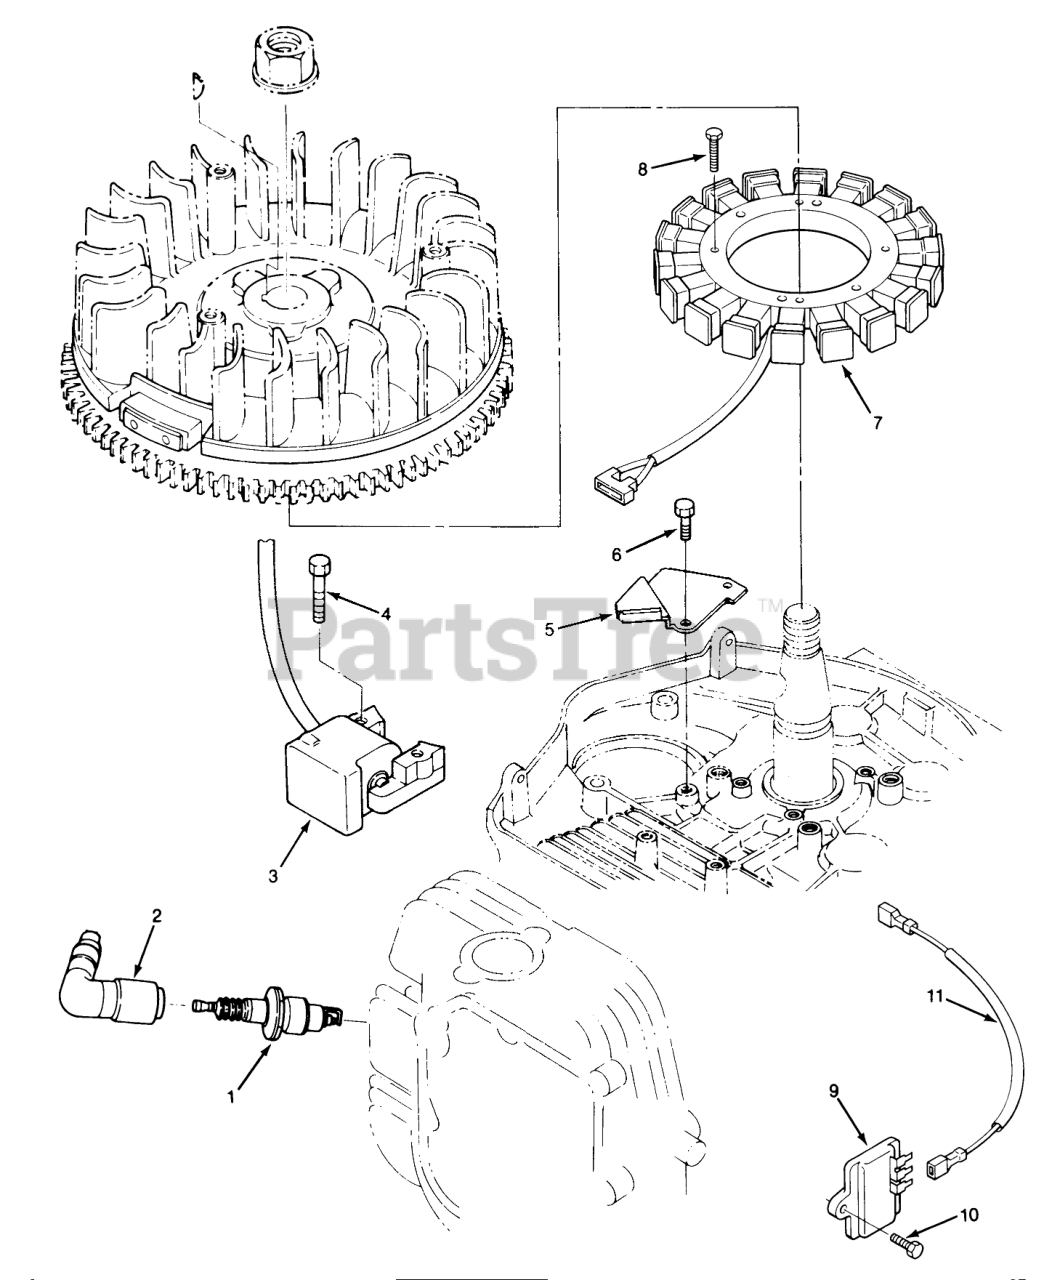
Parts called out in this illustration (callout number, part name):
1	Plug-Spark
3	COIL-IGNITION
4	HHSTB-M6 X 27MM
5	CLAMP-CORD
6	HHSTB-M6 X 14MM
7	STATOR
8	SCREW
9	Regulator
10	HHSTB-M6 X 14MM
11	HARNESS
